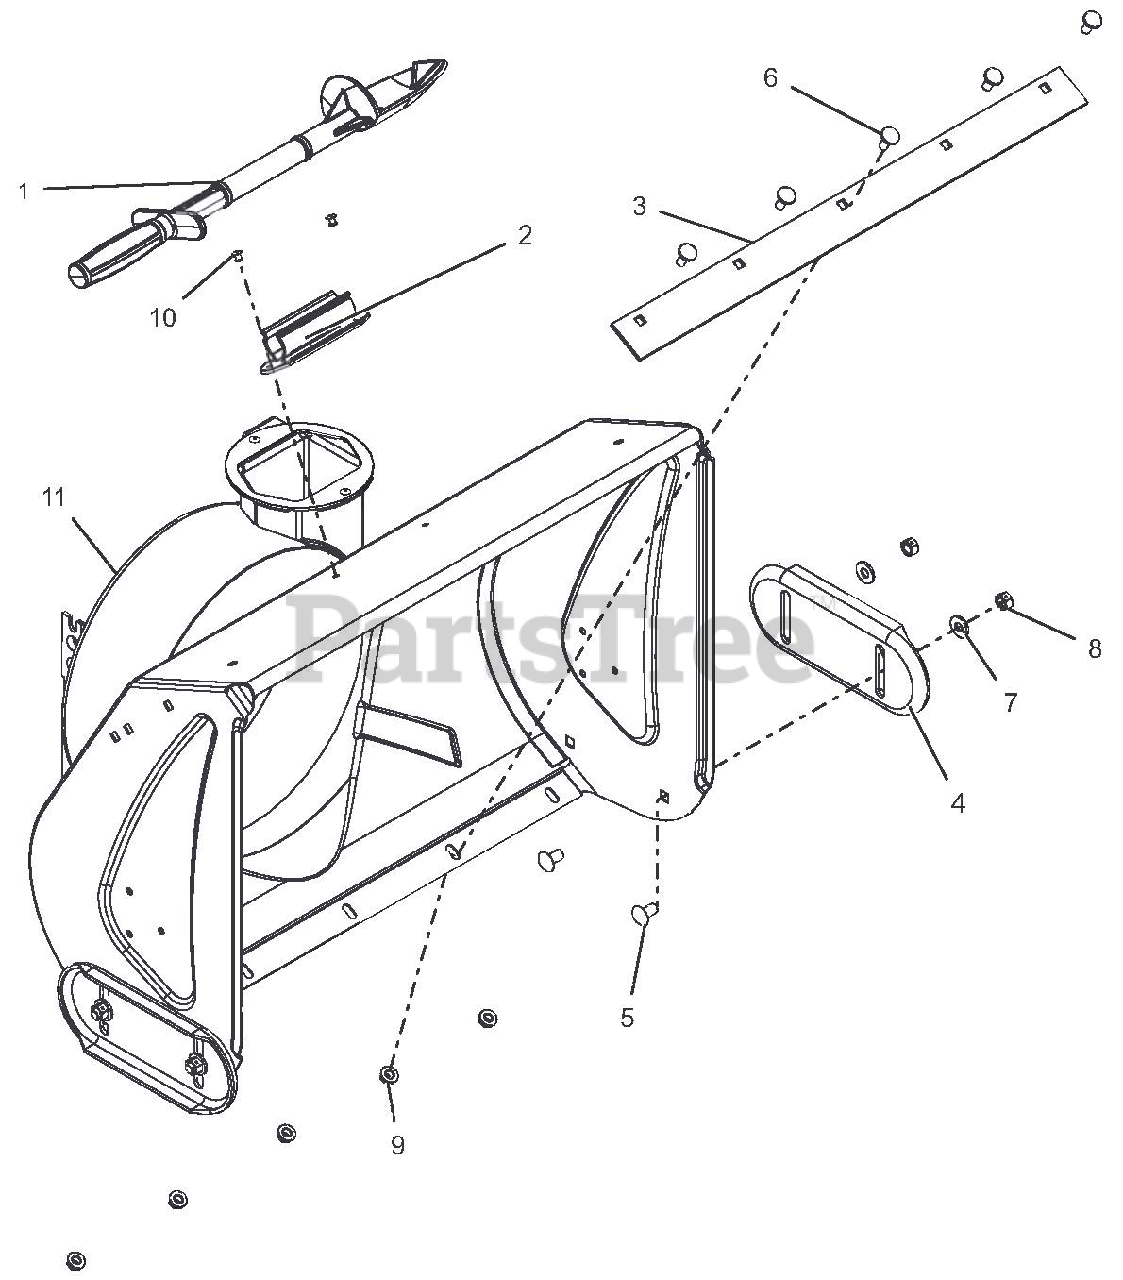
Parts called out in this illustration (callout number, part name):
1	DEVICE, SNOW CLEAN OUT
2	MOUNT, SNOW CLEAN OUT
3	SCRAPER BLADE, 24" COMPACT HI
4	SKID SHOE, REVERSIBLE
5	@BLT-RHDSSQNK .38-16X.75 G5YZ
6	BOLT, MODIFIED HEAD CARRIAGE
7	@WSHR-FL-STL.38X.875X.083 YWZC
8	@NUT-LK-CTR .38-16 YWZC
9	@NUT-LK-TOP-FLG .31-18 YWZC
10	RVT-POP .187 YZ
11	BLOWER HOUSING, 24"
